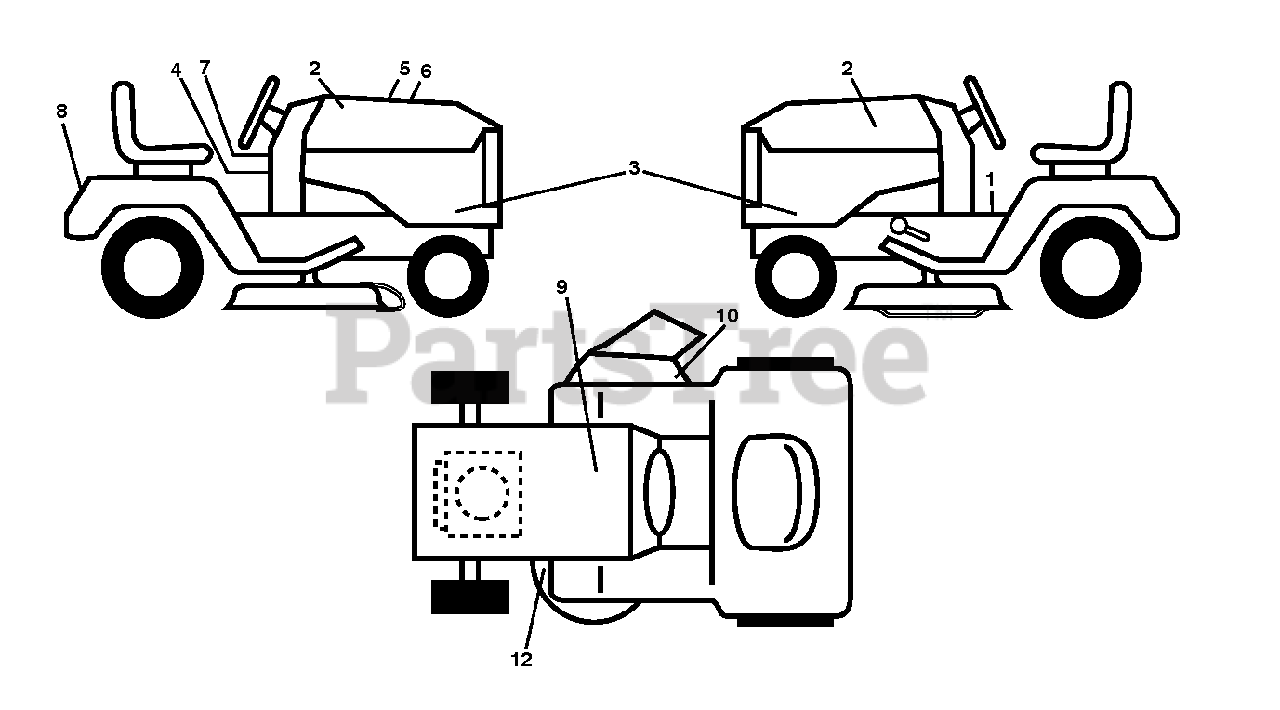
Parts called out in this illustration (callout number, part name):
1	DECAL.WARN.START.INSTRUCTIONS
2	RP.DECAL.BADGE.170MM.TEXTLOGO
3	DECAL.SDPNL.HUSQGT2.YTH12K26.2
4	DECAL, WARNING SPARK ARRESTOR
5	DECAL.WARNING.CUST.RESP.E85.
7	LABEL.EMISS.CA.HUSQ/LOWES.2011
8	DECAL.FENDER
9	DECAL BTRY SYMBOLS
10	DECAL.WARN.KEEP.HAND.AWAY
12	DECAL V BELT SCHEMATIC
